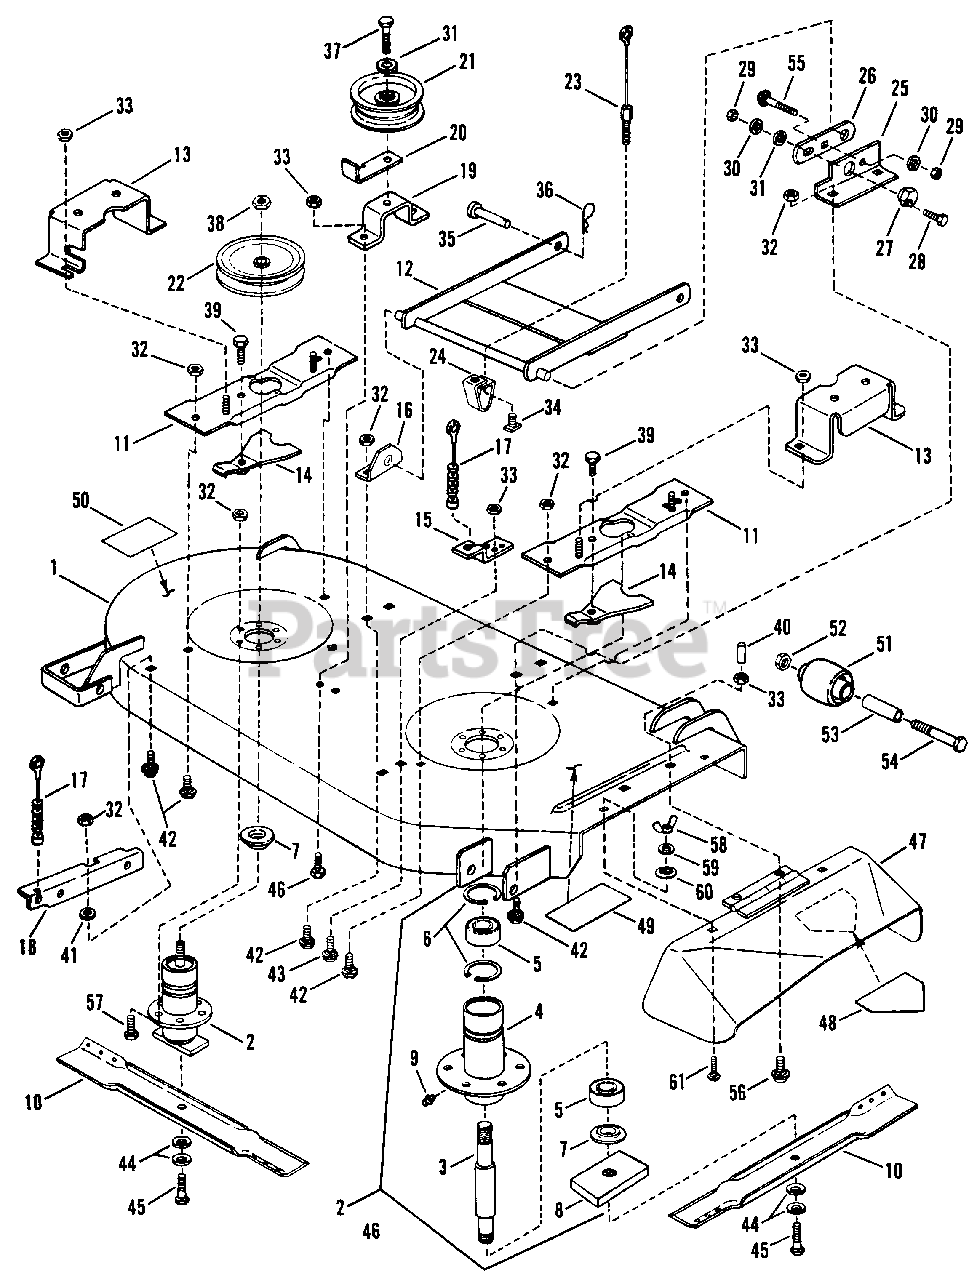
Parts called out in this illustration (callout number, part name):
1	DECK, Mower, 41" Shell
2	ASSEMBLY, Spindle
3	SPINDLE 6.5" Long
4	HOUSING, Spindle 5.1" Tall
5	BEARING, Spindle
6	RING, Retaining EXT 1.75"
7	WASHER, Spindle
8	HOLDER, Blade
9	FITTING, Lube (Press fit for .187 hole-no ball)
10	BLADE, 21" Cutter
11	ASSEMBLY, Rear Support
12	ASSEMBLY, Front Hanger 42"
13	GUARD, Pulley
14	ASSEMBLY, Spindle Lock
15	ASSEMBLY, Chain Support
16	BRACKET, Front Left Hanger
17	CABLE, Support (4.25", 8 Spacers)
18	ASSEMBLY, Rear Support
19	BRACKET, Idler Mount
20	GUIDE, Belt
21	PULLEY, Flat Idler 4.12" OD
22	PULLEY, Spindle "V" 5.75" OD .750" ID Hole
23	CABLE, Front Lift 6.12"
24	BRACKET, Front Lift Arm Hanger
25	BRACKET, Front Right
26	LINK, Adjustment
27	RING, Adjustment
28	SCREW, 3/8-16 x 1" Hex Head Cap
29	NUT, 3/8-16 Hex
30	WASHER, 3/8" Split Lock
31	WASHER, 3/8" Flat
32	NUT, 3/8-16 Hex Flange Lock
33	NUT, 5/16-18 Hex Flange Lock
34	T-NUT, 5/16-18
35	PIN, 1/2 x 1 3/8" Clevis
36	HAIRPIN, Cotter .148 x 2.62 YZ
37	SCREW, 3/8-16 x 1 1/2" Hex Cap
38	NUT, 3/4-16 Hex Jam
39	BOLT, 3/8-16 x 1" Hex Flange Lock
40	CAP, Vinyl
41	WASHER, 7/16 Flat
42	BOLT, 3/8-16 x 3/4" Carriage
43	BOLT, 5/16-18 x 3/4" Carriage
44	WASHER, 13/32 x 1 13/32" Dia., Cone
45	SCREW, 3/8-24 x 1 1/4" Hex Cap
46	BOLT, 5/16-18 x 3/4" Hex Flange Lock
47	DEFLECTOR, Side Chute
48	DECAL, Danger
49	DECAL, Caution (Deflector in Place)
50	DECAL, Caution (Rotating Blades)
51	WHEEL, Gage
52	LOCKNUT, 3/8-24 Hex
53	SPACER, .625 OD x .435 ID x 3" L
54	SCREW, 3/8-24 x 3 3/4" Hex Head Cap
55	BOLT, 3/8-16 x 3/4" Short Neck Carriage
56	BOLT, 5/16-18 x 1" Short Neck Carriage
57	BOLT, 3/8-16 x 3/4" Hex Flange Lock
58	WING-NUT, 5/16-18
59	WASHER, 5/16 Split Lock
60	RETAINER, 5/16 Bolt
61	BOLT, 5/16-18 x 5/8" Carriage
